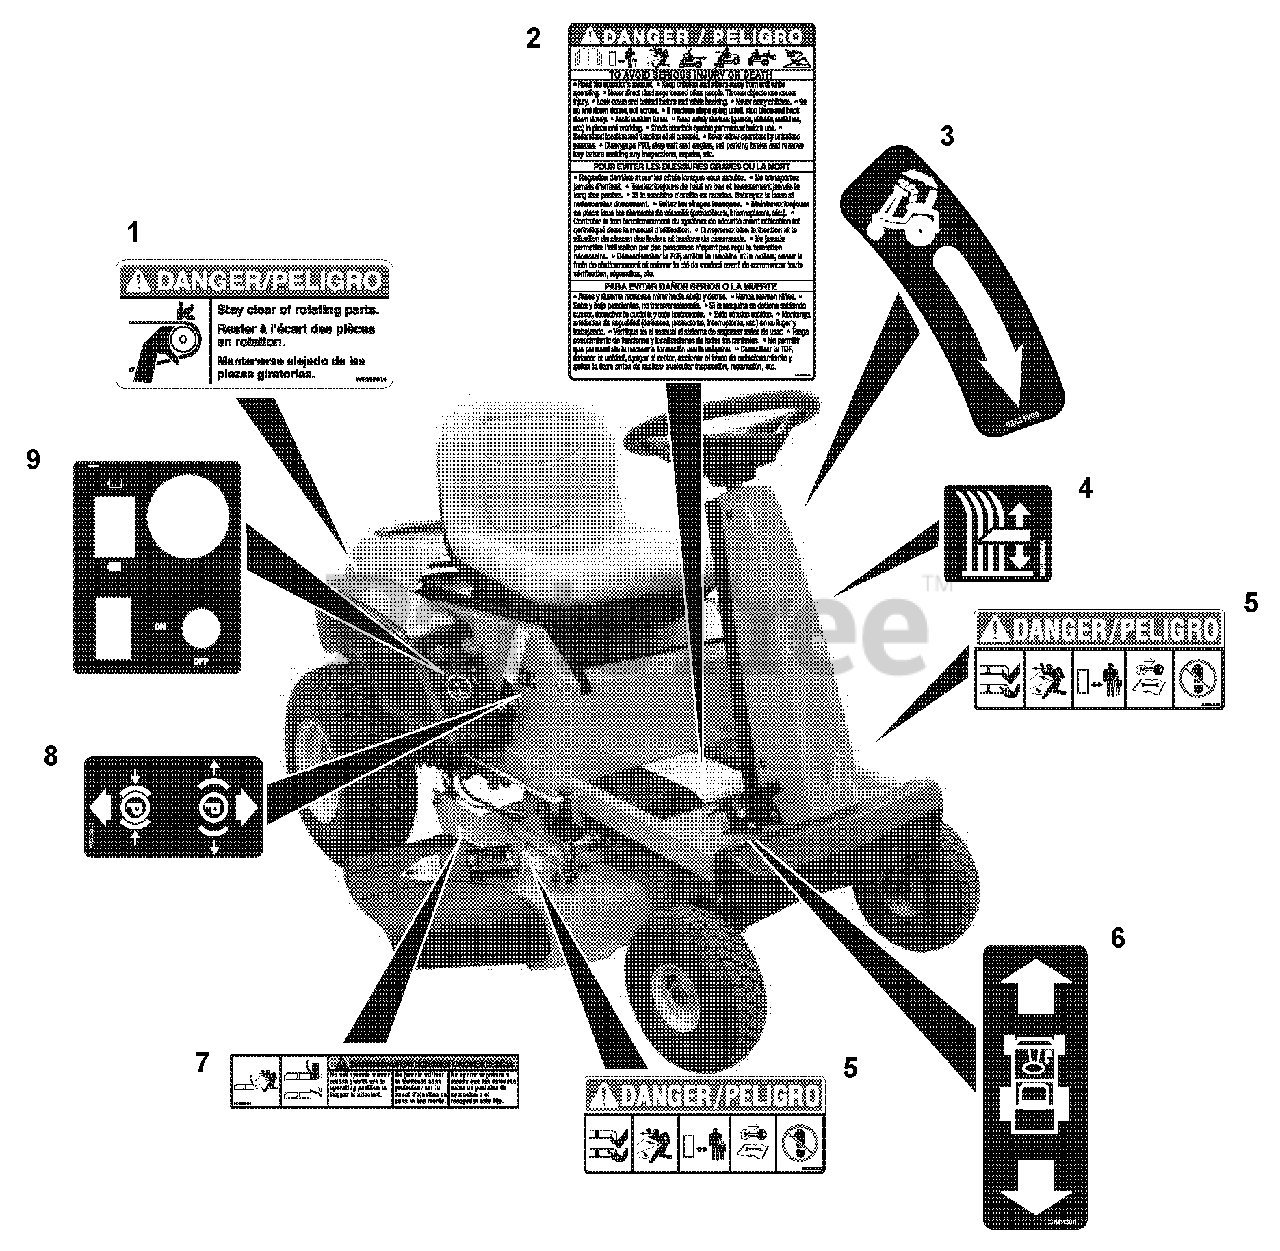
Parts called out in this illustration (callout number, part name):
1	DECAL-DANGER-BELT ROTATING
2	DECAL, DANGER BILINGUAL
3	GRAPHIC, SEAT RELEASE - AMP
4	DECAL-CUT HEIGHT
5	DECAL, MOWER PAN DANGER
6	DECAL, FWD/REV PEDAL
7	DECAL, FWD/REV PEDAL
8	DECAL, PARKING BRAKE LEVER
9	DECAL, CONTROL PANEL (AMP)
